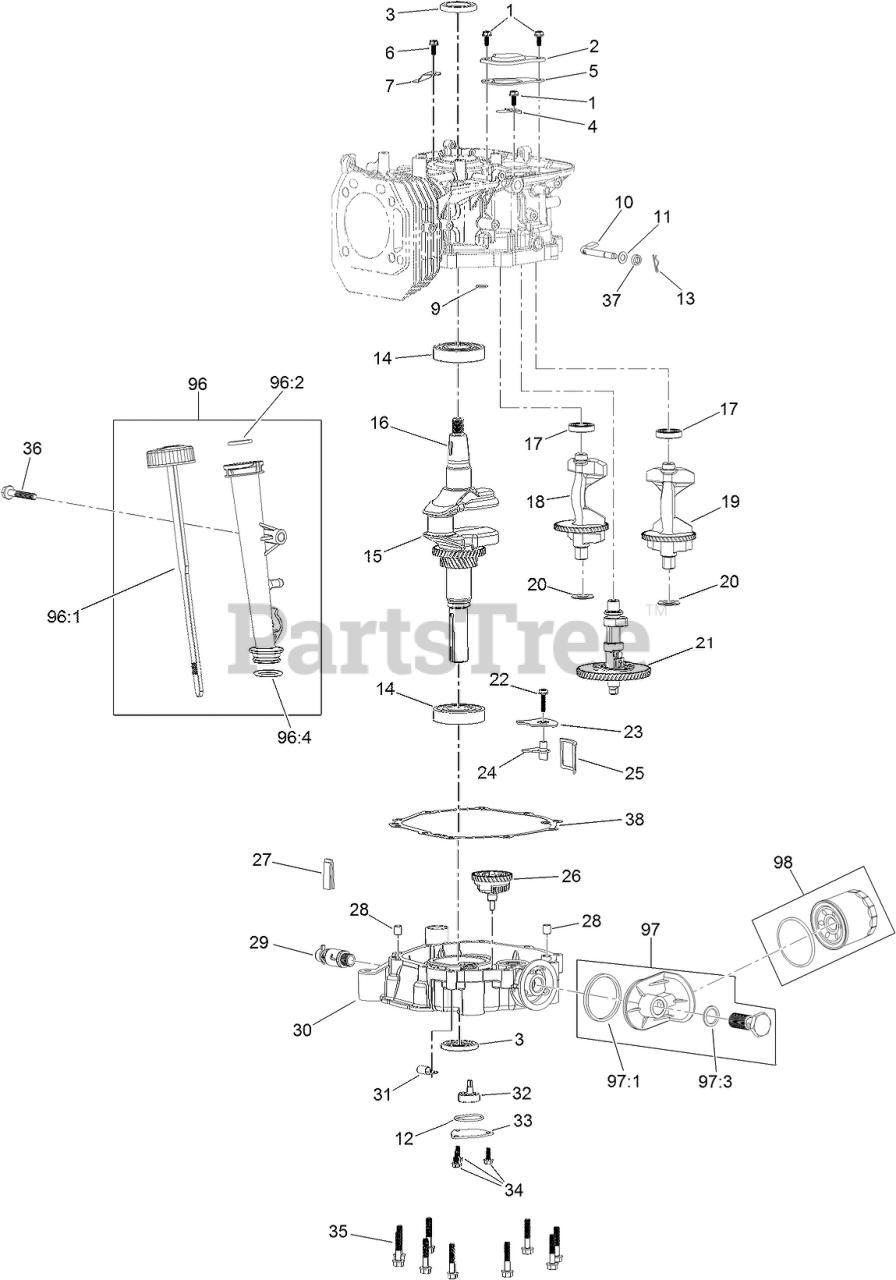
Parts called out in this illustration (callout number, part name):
1	SCREW-HHF
2	PLATE-BREATHER
3	SEAL-OIL
4	VALVE-REED
5	GASKET-BREATHER
6	SCREW-HHF
7	RETAINER
9	O-RING
10	SHAFT-GOVERNOR
11	WASHER-PLAIN
12	SEAL-PUMP, OIL
13	PIN-HAIR
14	BEARING-BALL
15	CRANKSHAFT
16	KEY-WOODRUFF
17	BEARING-BALL
18	SHAFT-BALANCE, R
19	SHAFT-BALANCE, L
20	WASHER
21	CAMSHAFT
22	SCREW-HHF
23	COVER-STRAINER, OIL
24	PLATE-BAFFLE, OIL
25	STRAINER-OIL
26	GEAR-GOVERNOR
27	DEFLECTOR-OIL, RUBBER
28	PIN-DOWEL
29	VALVE-DRAIN, OIL
30	COVER-CRANKCASE
31	CLAMP-HOSE
32	OIL PUMP ASM
33	COVER-PUMP, OIL
34	SCREW-HHF
35	SCREW-HHF
36	SCREW-HHF
37	SEAL-OIL
38	GASKET-CRANKCASE
96	DIPSTICK AND TUBE KIT
96:1	DIPSTICK ASM
96:2	O-RING
96:4	O-RING
97	OIL ADAPTOR KIT
97:1	SEAL-ADAPTOR, OIL
97:3	WASHER-FILTER, OIL
